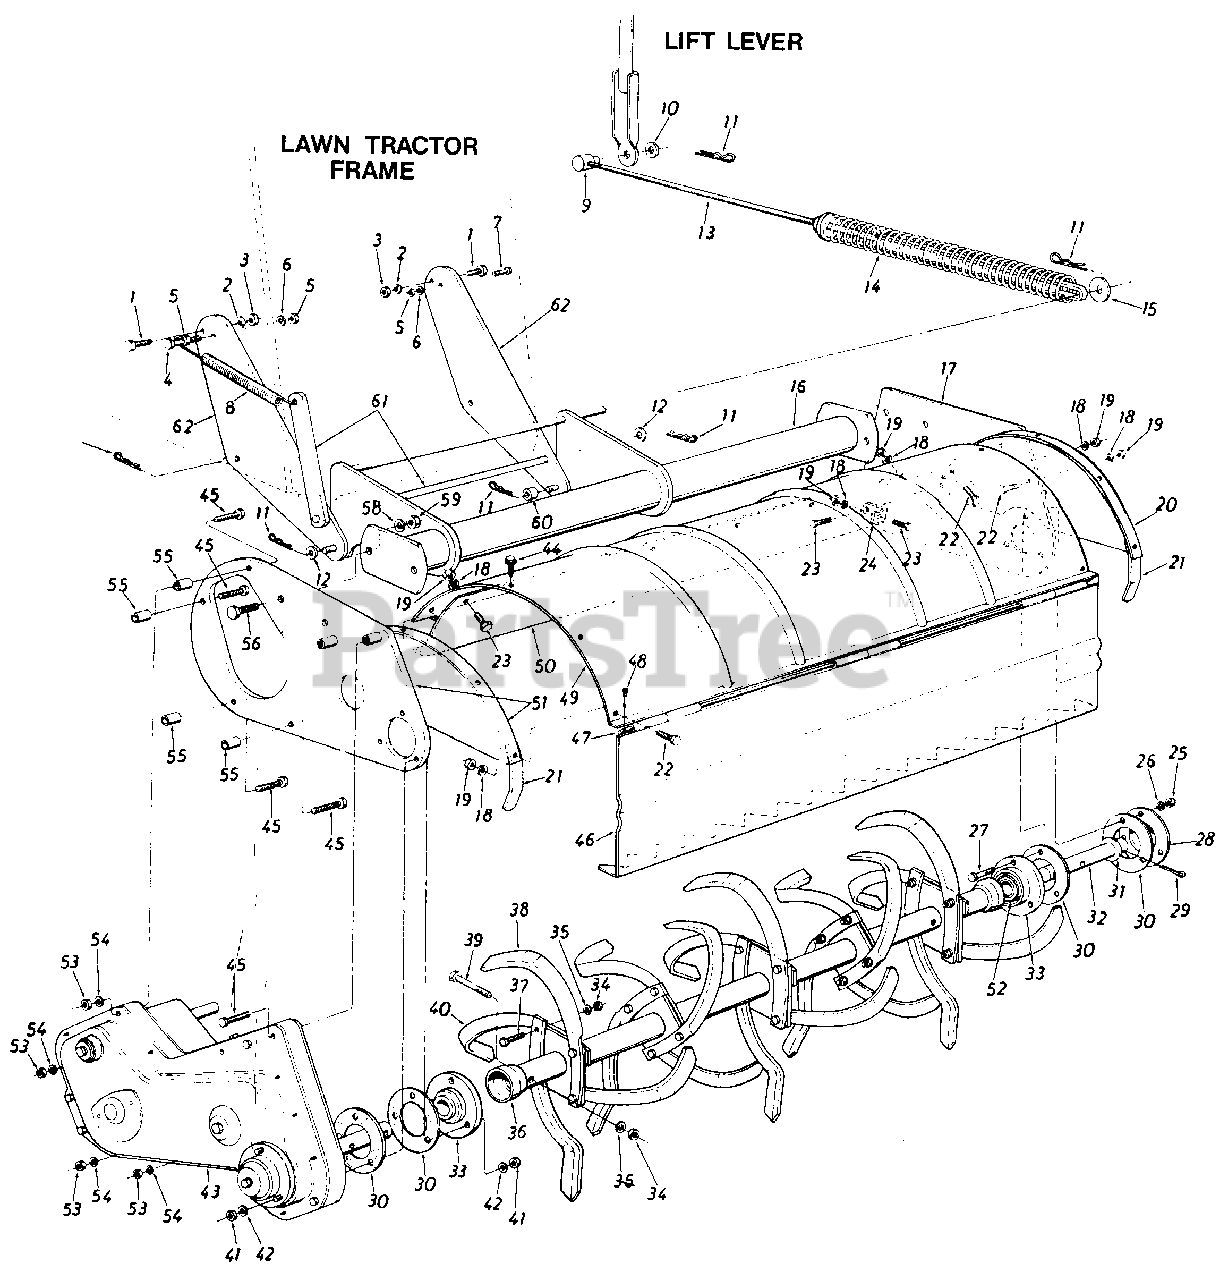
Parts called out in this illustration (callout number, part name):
1	Hex Bolt 3/8-24x .88" Lg.*
2	L.Wash. 3/8" I.D. Heavy Duty
3	Hex Nut 3/8-24Thd.*
4	Hex Bolt 5/16-24 x 1.50" Lg.*
5	Hex Nut 5/16-24 Thd.*
6	L.Wash. 5/16" I.D.*
7	Hex Bolt 5/16-24 x 1.00" Lg.*
8	Extension Spring .56" O.D. x 7.75" Lg.
9	Adjustment Ferrule 1/2-13 Thd.
10	Fl.Wash. .640" I.D. x 1.24" O.D. x .060
11	Intern. Coter Pin 1/2" Dia.
12	Fl.Wash. .510" I.D. x 1.0" O.D. x .060
13	Lift Rod Ass'y. 39.0" Lg.
14	Compression Spring 1.50" O.D. x 15.0" Lg.
15	Fl.Wash. .51" I.D. x 1.50" O.D. x .075
16	Pivot Bracket Assembly
19	Hex Nut5/16-24Thd.*
23	Hex Bolt 5/16-24 x .62" Lg. *
24	Chute Pivot Bracket
25	Hex Cent. L-Nut 5/16-18 Thd.
26	L.Wash. 5/16" I.D.*
27	Hex Bolt 5/16-18 x 1.0" Lg.(Grade 5)
30	Gasket for Brg. Housing
31	Fl.Wash. 1.25" I.D. x 2.00" O.D. x .06
32	Tine Shaft R.D. 1.25" Dia. x 6.25" Lg.
33	Bearing Housing w/Bearing
34	Hex Nut 3/8-24 Thd.*
35	L. Wash. 3/8" I.D. Heavy Duty
38	Tine 14" x 5/16"
39	Hex Bolt 3/8-24 x 2.25" L.*
41	Hex Cent. L.Nut 5/16-18Thd.
42	L.Wash. 5/16" I.D.*
43	ChainCase Ass'y. Comp.
44	Hex Wash. TT Tap. Scr. 5/16-18 x .62" Lg.
45	Hex Bolt 1/4-20 x 2.75" Lg.*
48	Coter Pin 1/8" Dia. x 1.00" Lg. *
53	Hex Nut 1/4-20 Thd.*
54	L.Wash. 1/4" I.D.*
55	Spacer.28" I.D. x .62" O.D. x .90" Lg.
56	Hex Bolt 1/2-13 x 1.00" Lg.*
58	L.Wash. 1/2" I.D.*
59	Hex Nut 1/2-13 Thd.*
60	Spacer.50" I.D. x 1.00" O.D. x .50" Lg.
61	Idler Bracket Support Arm Ass'y.
62	Pivot Bracket Support
